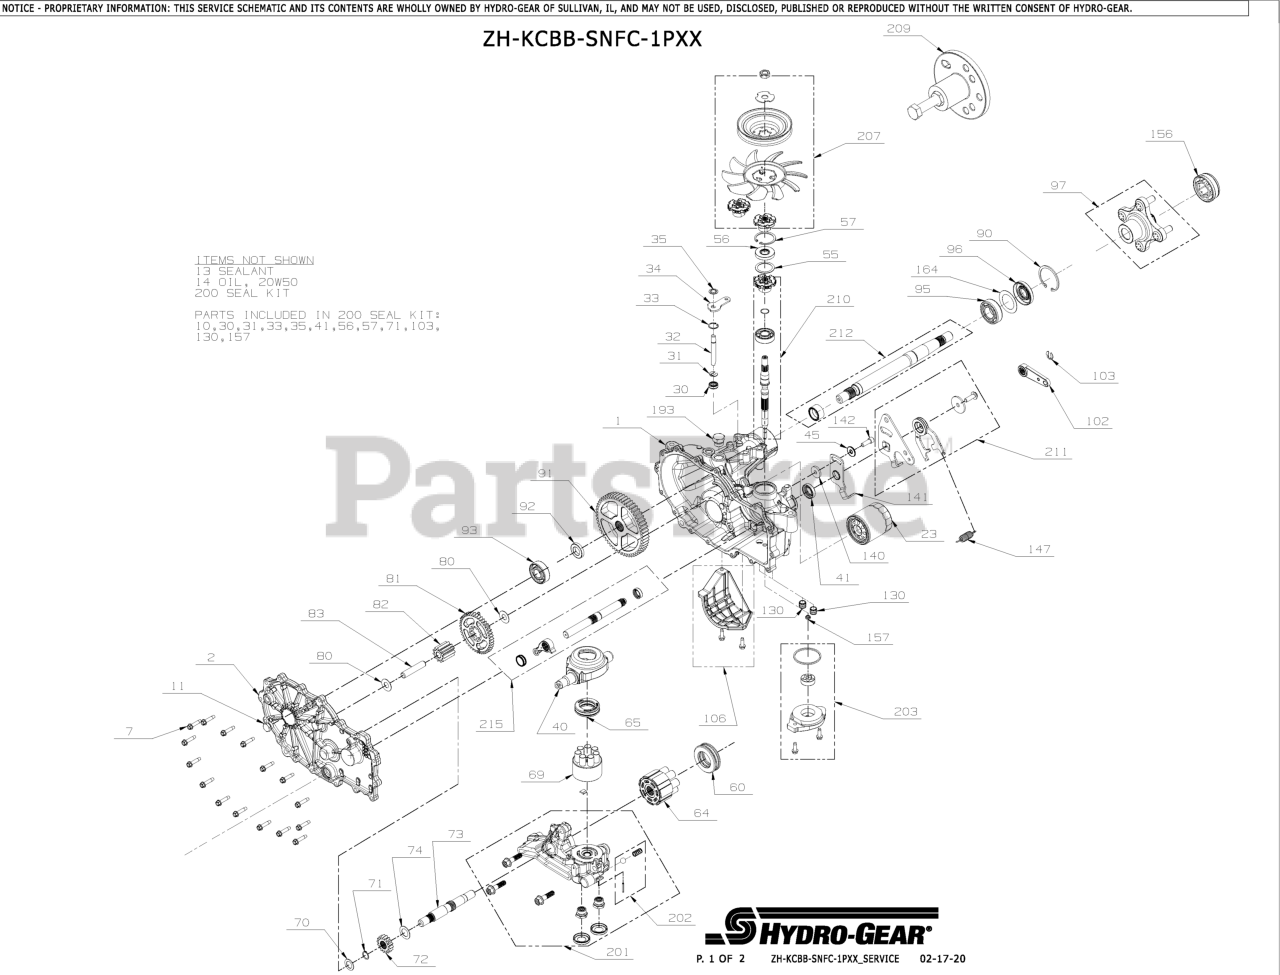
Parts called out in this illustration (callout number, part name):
1	KIT, HOUSING, MAIN, LH, CHRG, CNTL
2	KIT, SIDE COVER, LH
7	SCREW,HEX WASHER 1/4-20X1.125
11	PLUG EXT HEX VENT 9/16 18
13	SEALANT TUBE 10.1OZ.
14	FLUID, HYDRO 15W50 QT
14	FLUID, HYDRO 20W50 QT
23	FILTER, HYDRO-GEAR 2800 TRANS
30	SEAL, LIP .375X.75X.25
31	RING. RETAINING
32	ROD, BYPASS
33	RING, RET .750
34	ARM, BYPASS
35	RING, RTNG .
40	TRUNNION, SWASHPLATE
41	SEAL, LIP 18X32X7
55	WASHER 1.23X1.56X.04
56	SEAL, LIP 17X40X7
57	RING, RET 1.56 INT
60	HG THRUST BEARING (51462)
64	HG 16CC CYLINDER BLOCK (71579)
65	BEARING. THRUST 30 X 52 X 13
69	ASSY, BLOCK 7 PISTON
70	WASHER .63X1.0X.05
71	RING, RET 62 EXT
72	GEAR 16 TOOTH
73	SHAFT, MOTOR
74	WASHER .71 X 1.16 X .04
80	WASHER .5X1.0X.032
83	JACK SHAFT (PIN)
90	RING, RETAINING
91	GEAR 54 TOOTH
92	SPACER
93	KIT, BEARING
95	BEARING, BALL 25.4 X 52 X 15
96	SEAL, LIP
97	KIT, HUB 4 BOLT
102	HANDLE- ACTUATING
103	CLIP,BRAKE ARM HYDROGEAR 52027
106	KIT, FILTER GUARD
130	TUBE CHARGE TRIPLE ORING
141	ARM, NEUTRAL LEFT
142	SHCS 5/16-24X1 PATCH
147	SPRING, HYDROGEAR P/N 51833
156	CAP, AXLE
157	KIT GEROTOR SEAL
164	WASHER, 1.355 x 2.035 x .021 FLAT
200	KIT, SEAL
201	KIT-CENTER SETION- LH- CHRG
202	KIT CHARGE RELIEF
203	KIT, CHARGE
207	KIT- FAN/PULLEY
209	HUB PULLER 5 BLT
210	KIT INPUT SHAFT
211	KIT, RTN CW
212	KIT SHAFT AXLE
215	KIT, OUTBOARD, RH ROT A / LH ROT B
